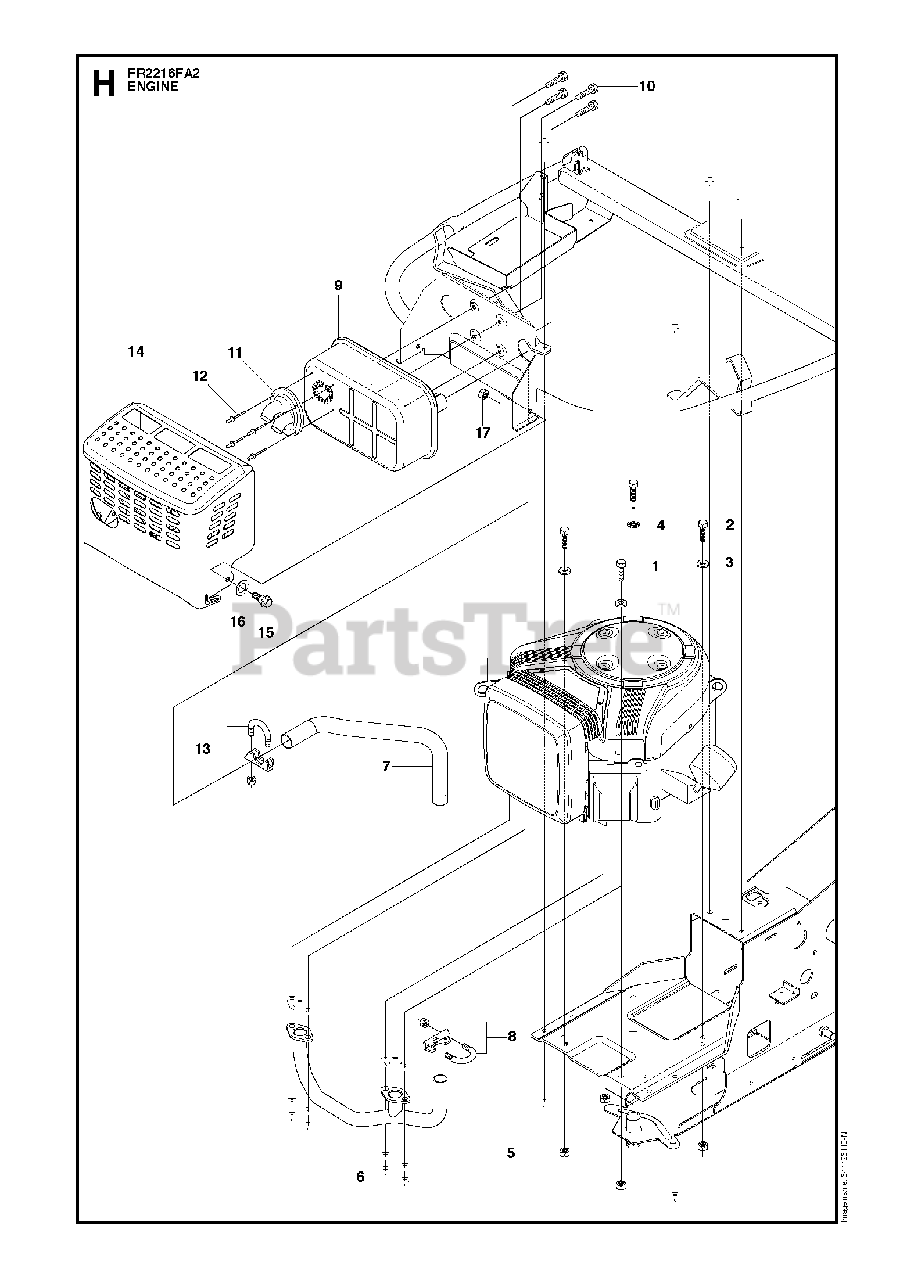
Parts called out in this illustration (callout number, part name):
3	WASHER BRB 8.4X17
5	LOCKNUT M8
8	CLAMP
10	SCREW
13	CLAMP
16	SPRINGWASHER
17	LOCKNUT M8
